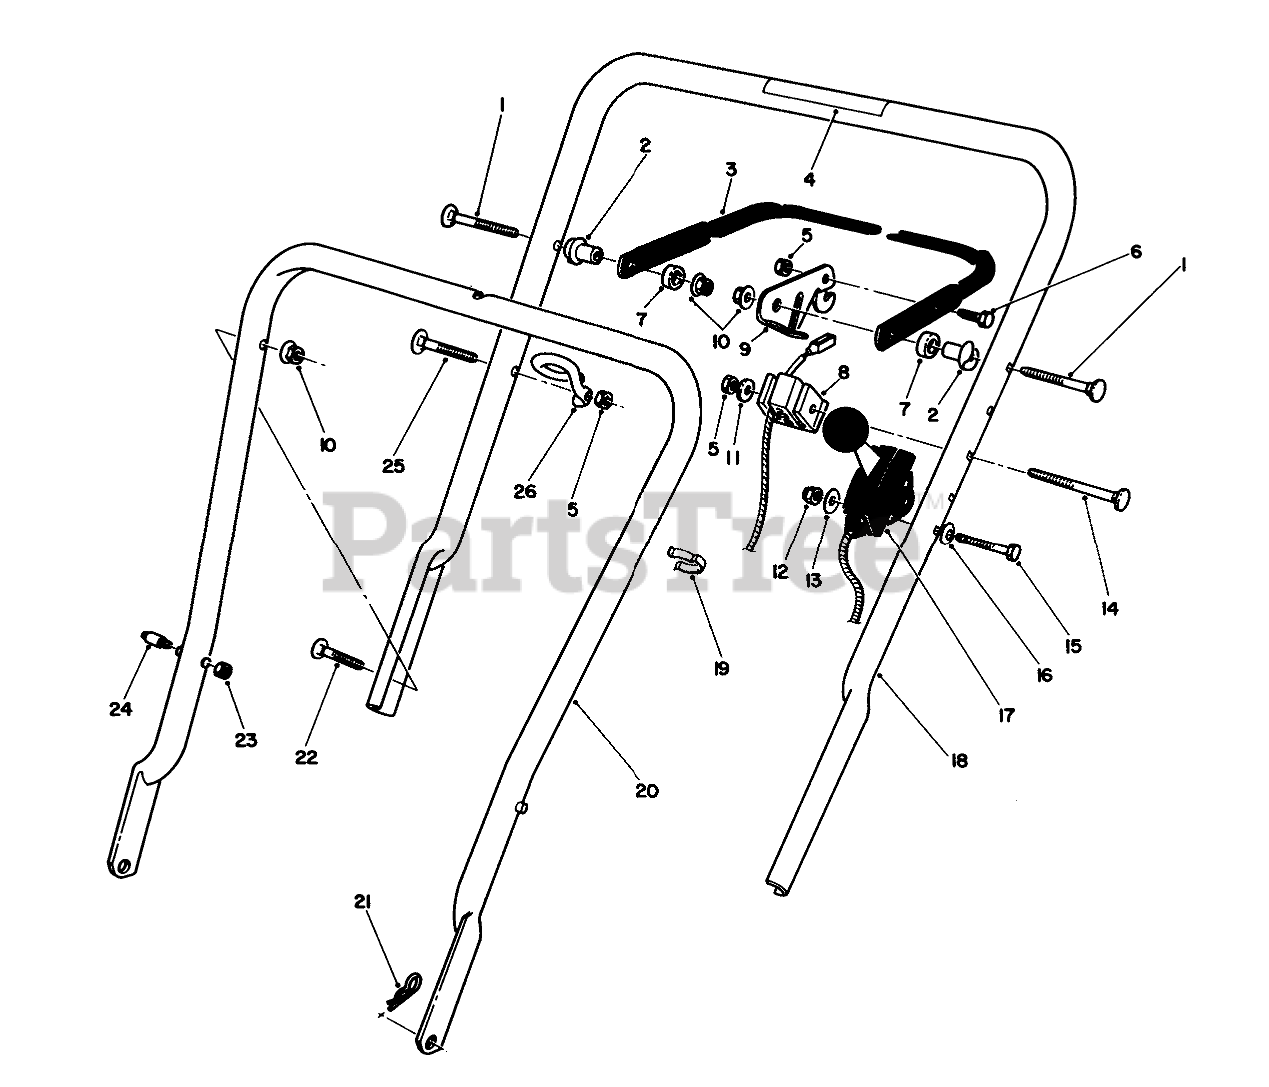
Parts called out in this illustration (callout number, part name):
1	5/16-18 X 2 HNDLE SCREW
2	SPACER-SUPPORT
3	Bar-Control
4	WARNING DECAL
5	NUT-LOCK, NI
6	SCREW-HH
7	SPACER-NYLON
8	SUPPORT-CABLE
9	LEVER-CONTROL
10	NUT-LOCK, NI
11	WASHER-FLAT
12	NUT-LOCK, NI
13	WASHER-FLAT
14	HANDLE SCREW
15	SCREW-SHH
16	Washer-Curved
17	THROTTLE CONT-SERVICE
18	Handle-Upper (Incl. Ref. #4)
19	BOWDEN CLIP
20	LOWER HANDLE ASM
21	PIN-COTTER, HAIR
22	SCREW
23	NUT-LOCK, NI
24	HANDLE PIN
25	HANDLE SCREW
26	Guide
